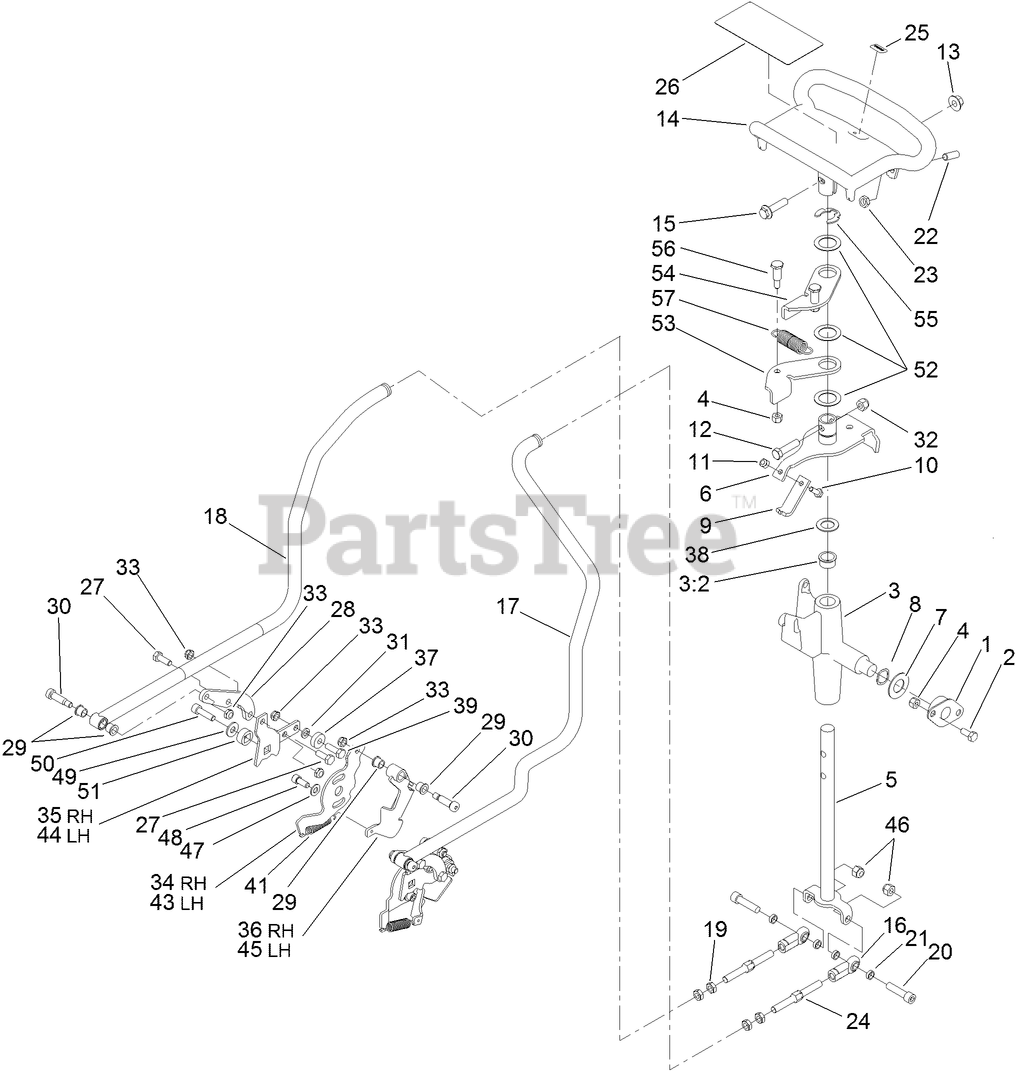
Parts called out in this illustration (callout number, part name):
1	BEARING
2	SCREW-HH
3	CONTROL SUPPORT ASM
3:2	BEARING-FLANGE
4	NUT-LOCK, NI
5	ROD-DRIVE
6	LEVER-PIVOT
7	WASHER-FLAT
8	WASHER-SPRING, WAVE
9	PLATE-NEUTRAL
10	SCREW-HH
11	NUT-LOCK, NI
12	SCREW-HH
13	NUT-FLANGE
14	HANDLE-CONTROL
15	SCREW-HHF
16	JOINT-BALL END, LH
17	ROD-CONTROL, LH
18	ROD-CONTROL, RH
19	NUT-HJ
20	SCREW-HSH
21	SPACER-PLATE, RETAINING
22	SCREW-SET
23	NUT-JAM
24	LINK-CONTROL, ADJUSTMENT
25	DECAL
26	DECAL-TRACTION
27	SCREW-HH
28	PLATE-ADAPTER, CONTROL, RH
29	BUSHING-FLANGE
30	BOLT-SHOULDER
31	WASHER-LOCK
32	NUT-LOCK, NI
33	NUT-LOCK, NI
34	PLATE-BASE, RH
35	PLATE-ARM, RETURN
36	PIVOT-RH
37	BEARING-BALL
38	WASHER-THRUST
39	SCREW-HH
41	SPRING-EXTENSION
43	PLATE-BASE, LH
44	PLATE-ARM, RETURN, LH
45	PIVOT-LH
46	NUT-LOCK, NI
47	WASHER-BELLEVILLE
48	SCREW-HSH
49	WASHER-FLAT
50	SCREW-HSH
51	LOCK-TRUNION
52	WASHER-PLAIN
53	LEVER-RETURN, RH
54	LEVER-RETURN, LH
55	RING-RETAINING
56	SCREW-SHOULDER
57	SPRING-EXTENSION
